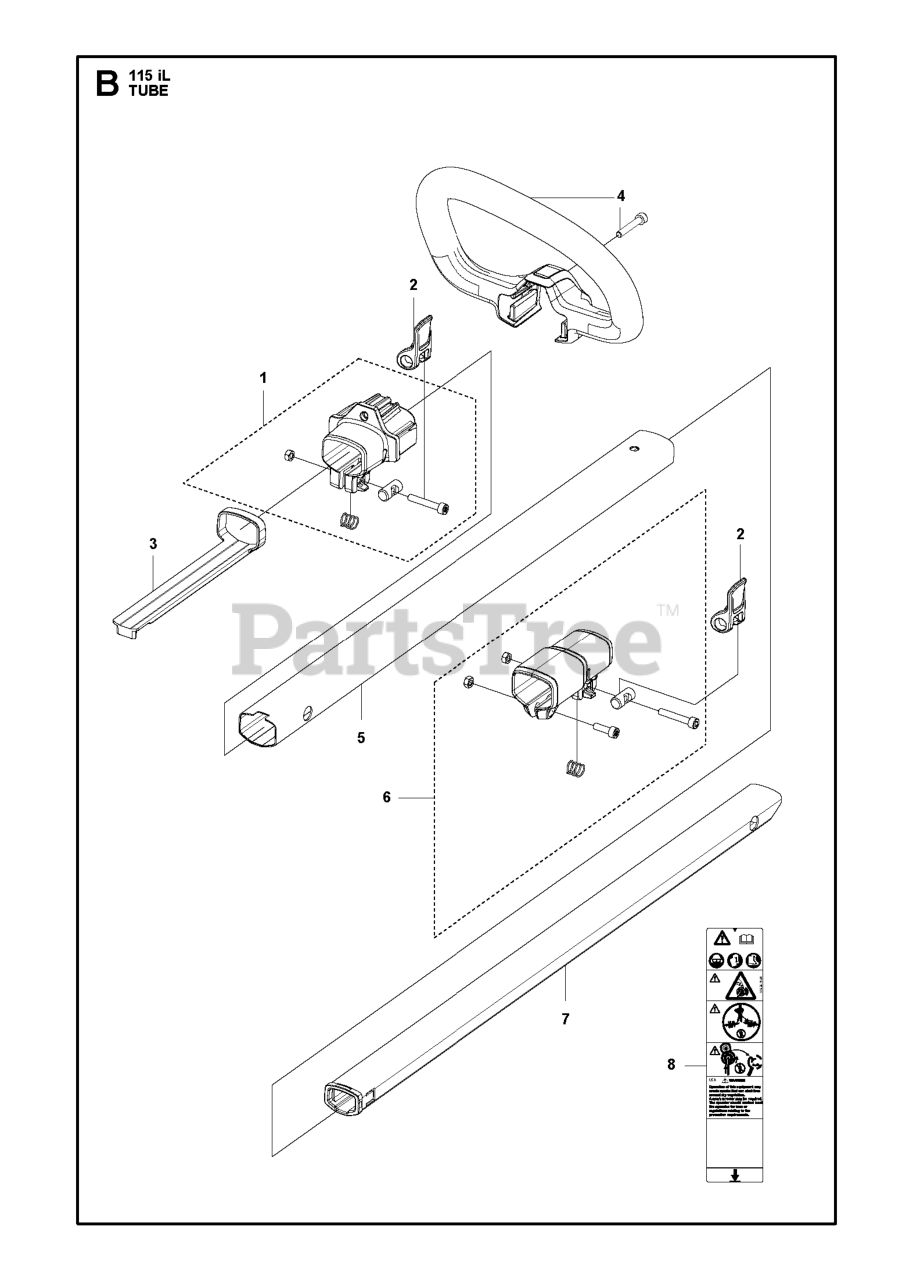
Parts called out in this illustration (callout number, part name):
1	COUPLING ,FRONT HANDLE ASSY
3	SPACER FRONT HANDLE
4	HANDLE ,FRONT HANDLE ASSY
5	TUBE
5	TUBE BIG
6	COUPLING ,TUBE COUPLING ASSY
7	TUBE ASSY SMALL TUBE ASSEMBLY
8	LABEL WARNING TRIMMERS AND BRU
